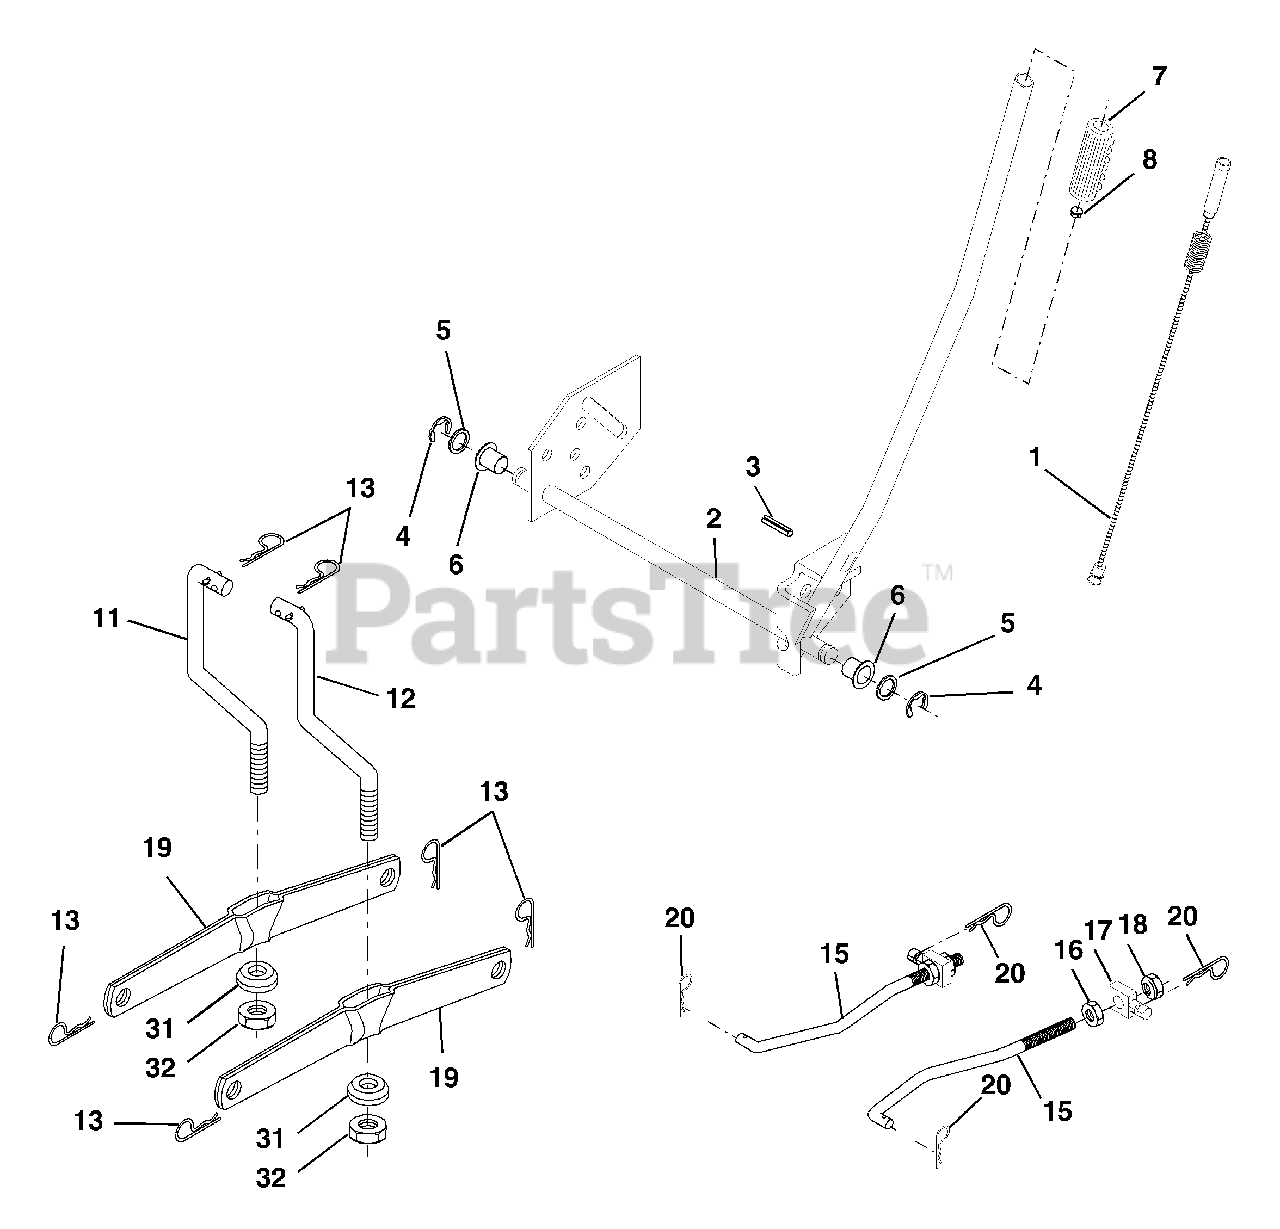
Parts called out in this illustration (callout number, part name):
1	Wire Asm Inner/Sprg w/Plunger
2	Shaft Asm Lift
3	Pin Groove
4	E Ring #5133-62
5	Washer 21/32 x 1 x 21 Ga.
6	Bearing Nylon
7	Grip Handle
8	Button Plunger
11	Link Lift Lh
12	Link Lift Rh
13	Retainer Spring
15	Link Front
16	Nut Jam Hex 1/2-13 Unc
17	Trunnion
18	Nut Lock w/Wsh 1/2-13 Unc
19	Arm Suspension Rear
20	Retainer Spring
31	Bearing Pvt Lift
32	Nut Crownlock 3/8-24
